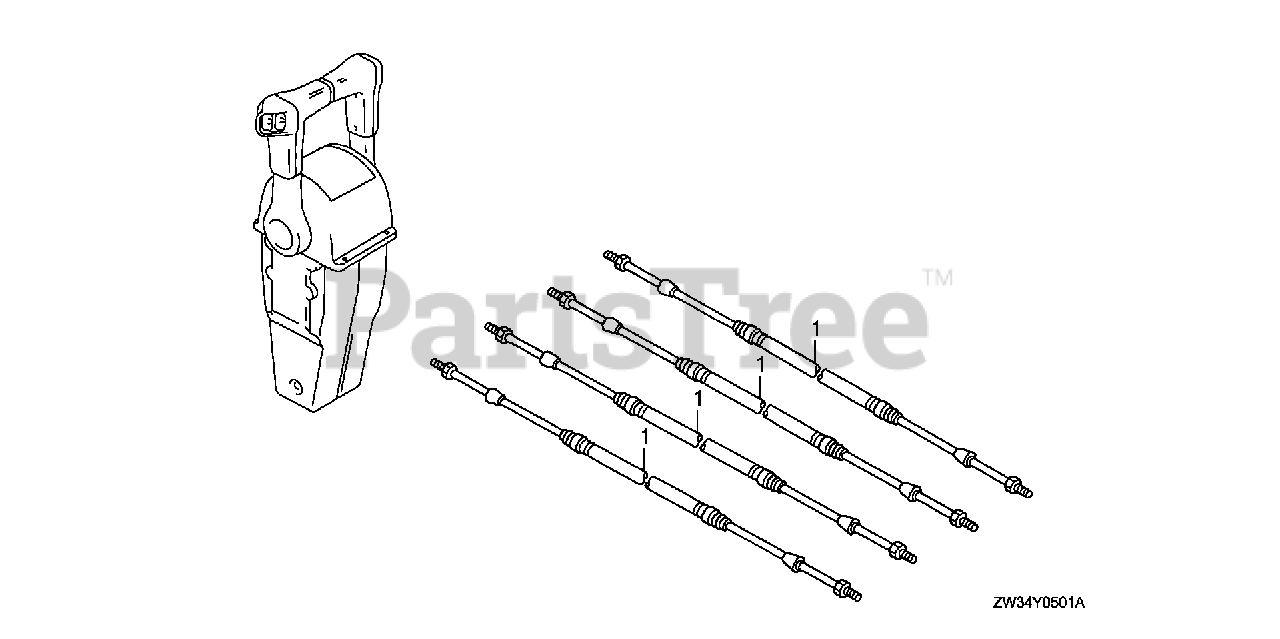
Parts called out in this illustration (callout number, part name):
1	CABLE, REMOTE CONTROL (10') (LOW FRICTION)
1	CABLE ASSY., PUSH-PULL (33C-5FT)
1	CABLE, REMOTE CONTROL (11') (LOW FRICTION)
1	CABLE ASSY., PUSH-PULL (33C-6FT)
1	CABLE, REMOTE CONTROL (12') (LOW FRICTION)
1	CABLE ASSY., PUSH-PULL (33C-7FT)
1	CABLE, REMOTE CONTROL (13') (LOW FRICTION)
1	CABLE ASSY., PUSH-PULL (33C-8FT)
1	CABLE, REMOTE CONTROL (14') (LOW FRICTION)
1	CABLE ASSY., PUSH-PULL (33C-9FT)
1	CABLE, REMOTE CONTROL (15') (LOW FRICTION)
1	CABLE ASSY., PUSH-PULL (33C-10FT)
1	CABLE, REMOTE CONTROL (16') (LOW FRICTION) (NOT AVAILABLE)
1	CABLE ASSY., PUSH-PULL (33C-11FT)
1	CABLE, REMOTE CONTROL (17') (LOW FRICTION)
1	CABLE ASSY., PUSH-PULL (33C-12FT)
1	CABLE, REMOTE CONTROL (18') (LOW FRICTION) (NOT AVAILABLE)
1	CABLE ASSY., PUSH-PULL (33C-13FT)
1	CABLE, REMOTE CONTROL (19') (LOW FRICTION)
1	CABLE ASSY., PUSH-PULL (33C-14FT)
1	CABLE, REMOTE CONTROL (20') (LOW FRICTION) (NOT AVAILABLE)
1	CABLE ASSY., PUSH-PULL (33C-15FT)
1	CABLE, REMOTE CONTROL (21') (LOW FRICTION)
1	CABLE ASSY., PUSH-PULL (33C-16FT)
1	CABLE, REMOTE CONTROL (22') (LOW FRICTION) (NOT AVAILABLE)
1	CABLE ASSY., PUSH-PULL (33C-17FT)
1	CABLE, REMOTE CONTROL (23') (LOW FRICTION)
1	CABLE ASSY., PUSH-PULL (33C-18FT)
1	CABLE, REMOTE CONTROL (24') (LOW FRICTION) (NOT AVAILABLE)
1	CABLE ASSY., PUSH-PULL (33C-19FT)
1	CABLE, REMOTE CONTROL (25') (LOW FRICTION)
1	CABLE ASSY., PUSH-PULL (33C-20FT)
1	CABLE, REMOTE CONTROL (26') (LOW FRICTION)
1	CABLE ASSY., PUSH-PULL (33C-21FT)
1	CABLE, REMOTE CONTROL (27') (LOW FRICTION)
1	CABLE ASSY., PUSH-PULL (33C-22FT)
1	CABLE, REMOTE CONTROL (28') (LOW FRICTION) (NOT AVAILABLE)
1	CABLE ASSY., PUSH-PULL (33C-23FT)
1	CABLE, REMOTE CONTROL (29') (LOW FRICTION)
1	CABLE ASSY., PUSH-PULL (33C-24FT)
1	CABLE, REMOTE CONTROL (30') (LOW FRICTION) (NOT AVAILABLE)
1	CABLE ASSY., PUSH-PULL (33C-25FT)
1	CABLE, REMOTE CONTROL (31') (LOW FRICTION)
1	CABLE ASSY., PUSH-PULL (33C-26FT)
1	CABLE, REMOTE CONTROL (32') (LOW FRICTION) (NOT AVAILABLE)
1	CABLE ASSY., PUSH-PULL (33C-27FT)
1	CABLE, REMOTE CONTROL (33') (LOW FRICTION)
1	CABLE ASSY., PUSH-PULL (33C-28FT)
1	CABLE, REMOTE CONTROL (34') (LOW FRICTION) (NOT AVAILABLE)
1	CABLE ASSY., PUSH-PULL (33C-29FT)
1	CABLE, REMOTE CONTROL (35') (LOW FRICTION)
1	CABLE ASSY., PUSH-PULL (33C-30FT)
1	CABLE ASSY., PUSH-PULL (33C-31FT)
1	CABLE ASSY., PUSH-PULL (33C-32FT)
